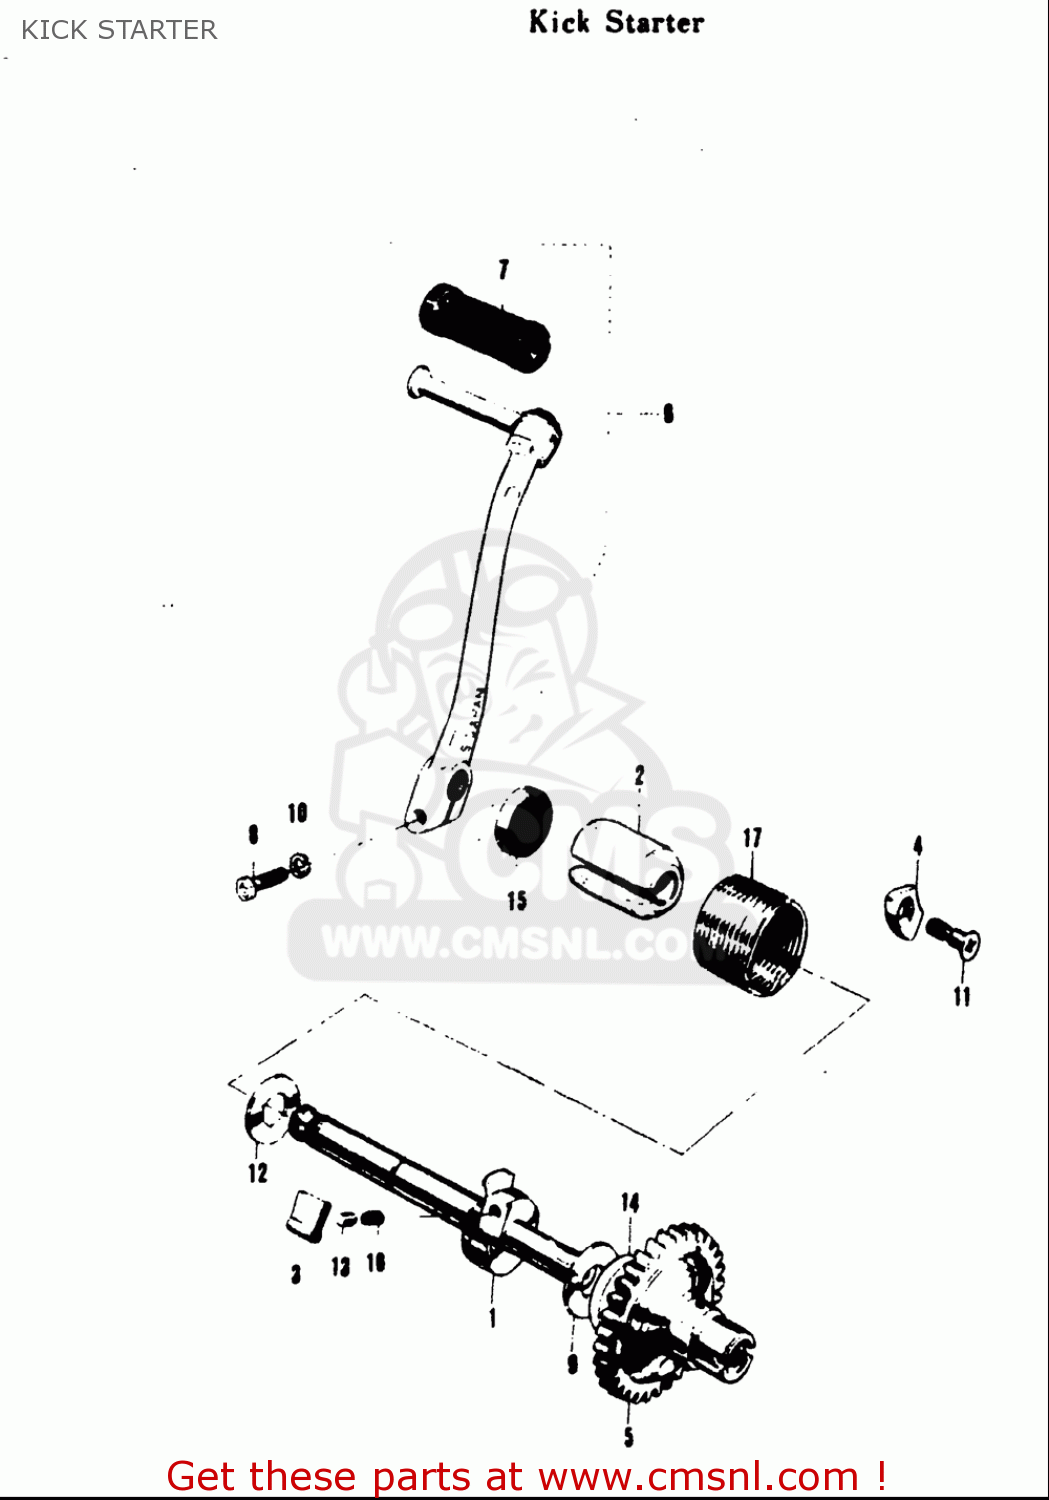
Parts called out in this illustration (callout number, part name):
2	GUIDE,KICK STARTER SFT SPRING
4	LIFTER,KICK STARTER PAWL
7	RUBBER,KICK STARTER PEDAL
8	BOLT
9	WASHER
10	WASHER,LOCK
11	SCREW(6X19)
12	WASHER(16X30X1)
13	PIN(5X15.5)
15	SEAL,OIL(16X30X8)
16	SPRING
